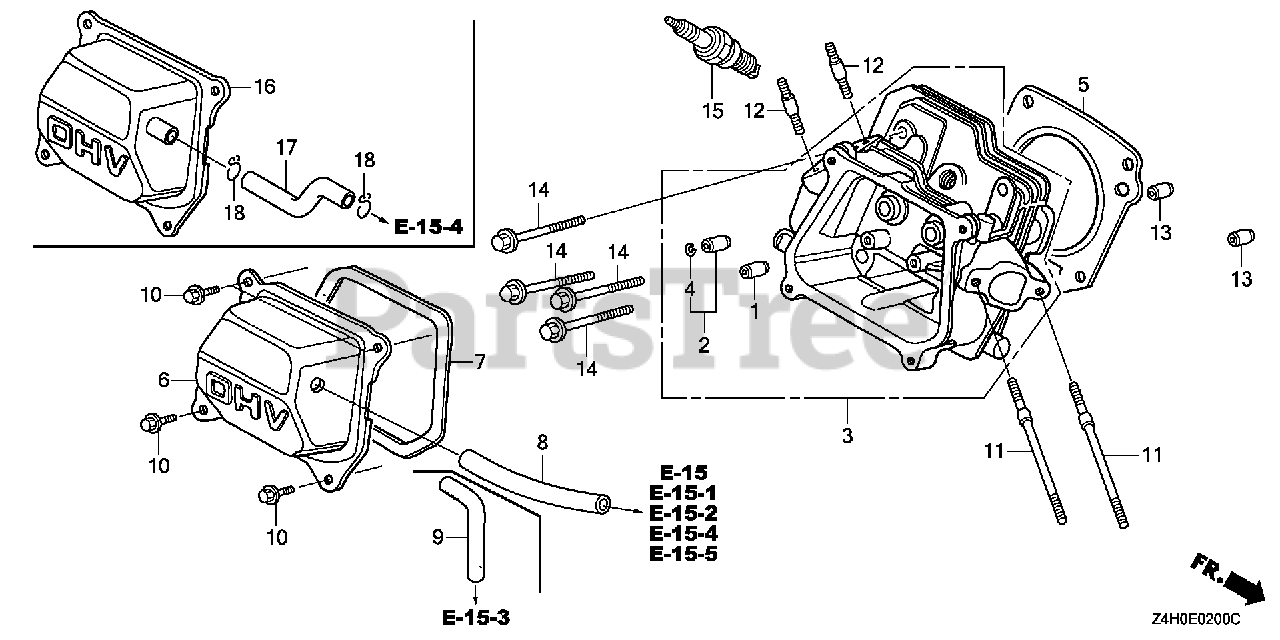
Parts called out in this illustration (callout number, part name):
1	GUIDE, VALVE (OVER SIZE) Use from Engine SN 6324986.
2	GUIDE, EX. VALVE (OS)
3	CYLINDER HEAD
4	CLIP, VALVE GUIDE Use from Engine SN 1231803.
5	GASKET, CYLINDER HEAD
5	GASKET, CYLINDER HEAD (THAI LEAKLESS)
6	COVER, HEAD
7	GASKET, CYLINDER HEAD COVER
8	TUBE, BREATHER
10	BOLT, FLANGE (6X12) (CT200)
11	BOLT, STUD (6X109)
12	BOLT, STUD (8X32)
13	PIN A, DOWEL (10X16)
14	BOLT, FLANGE (8X55)
15	SPARK PLUG (BPR5ES) (NGK)
15	SPARK PLUG (BPR6ES) (NGK)
